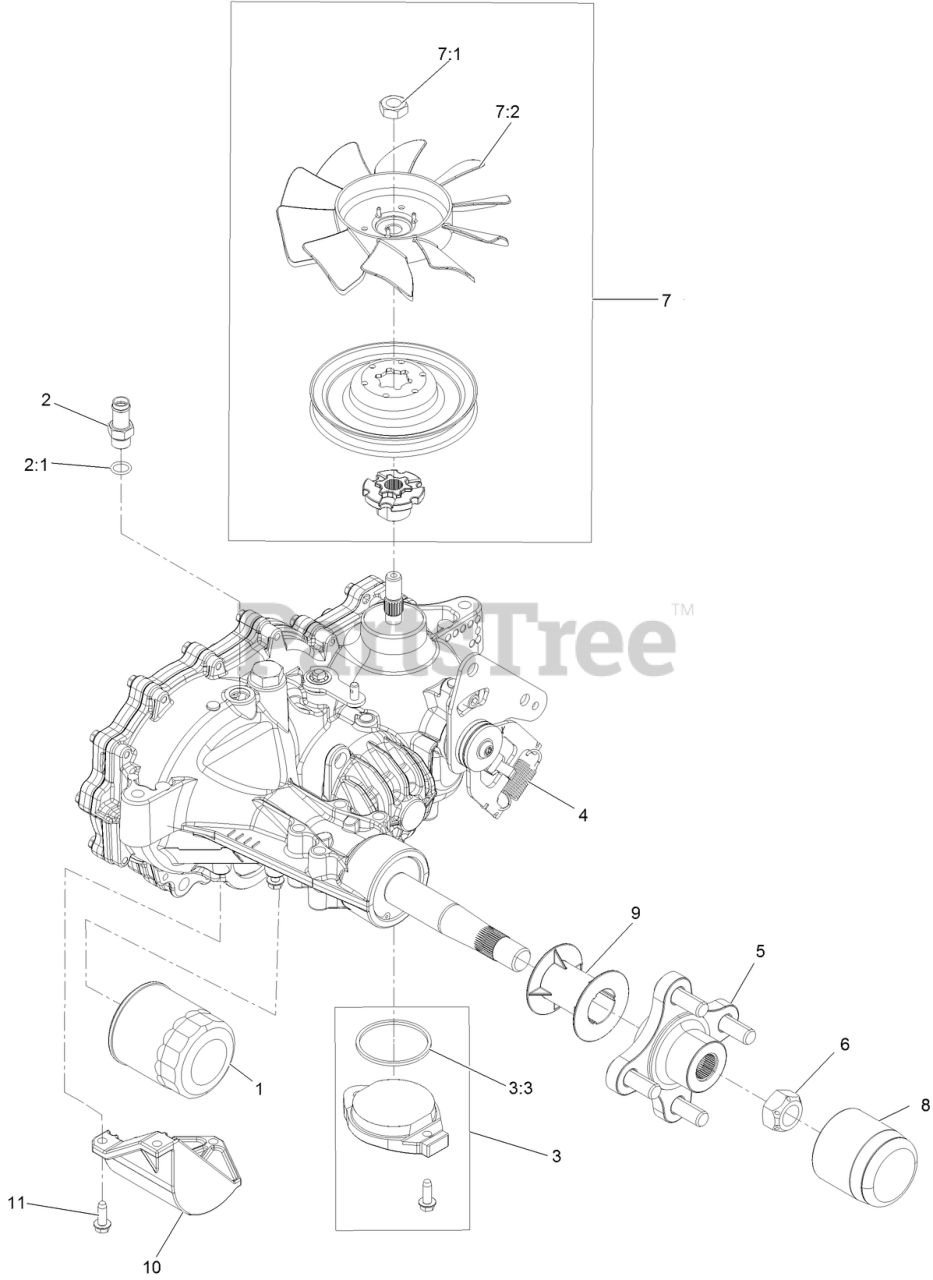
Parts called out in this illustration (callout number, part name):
1	ELEMENT-OIL FILTER, HYD
2	ADAPTER-STRAIGHT
2:1	O-RING
3	CHARGE KIT
3:3	O RING-SEAL
4	SPRING-EXTENSION
5	HUB-OFFSET
6	NUT-HUB
7	FAN AND PULLEY KIT
7:1	NUT-HJ
8	CAP-AXLE, LONG
9	TUBE-AXLE
10	GUARD-FILTER, RH
